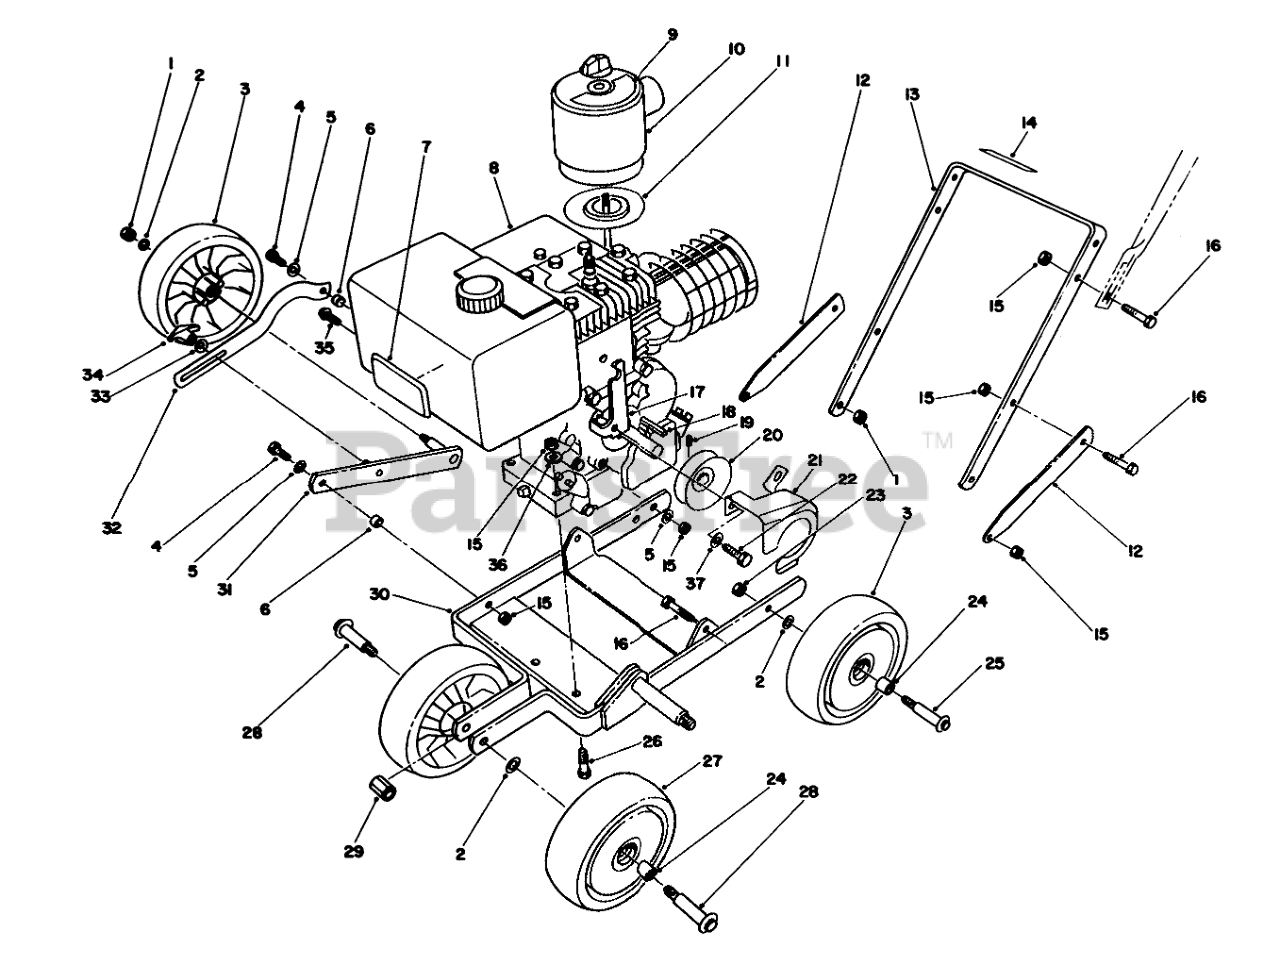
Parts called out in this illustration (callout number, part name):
1	NUT-LOCK
2	WASHER
3	Wheel & Tire Assembly (Incl. Ref. #24)
4	SCREW-HH
5	WASHER-FLAT
6	WHEEL MT BUSHING
7	TORO LOGO PLT
8	Engine-3 hp.
9	DECAL - WARNING
10	AIR CLEANER COVER WA
11	AIR CLEANER BASE
12	SUPPORT HANDLE
13	LOWER HANDLE
14	Decal-Warning
15	NUT-LOCK, NI
16	SCREW-HH
17	SPRING BRACKET
19	SCREW-SET
20	PULLEY (3.5 HP)
21	ENG. PULLEY GUARD
22	SCREW-HH
23	NUT-HEX
24	BUSHING
25	WHEEL BOLT
26	SCREW-HH
27	Wheel & Tire Assembly (Incl. Ref. #24)
28	BOLT-WHEEL
29	HEX SPACER
30	Frame-Edger
31	WHEEL MOUNT WA
32	AXLE LINK
33	BELLEVILLE SPRING WASHE
35	3/8-24 X 1.00HEX BU. HD
36	WASHER-PLAIN
37	WASHER-LOCK
